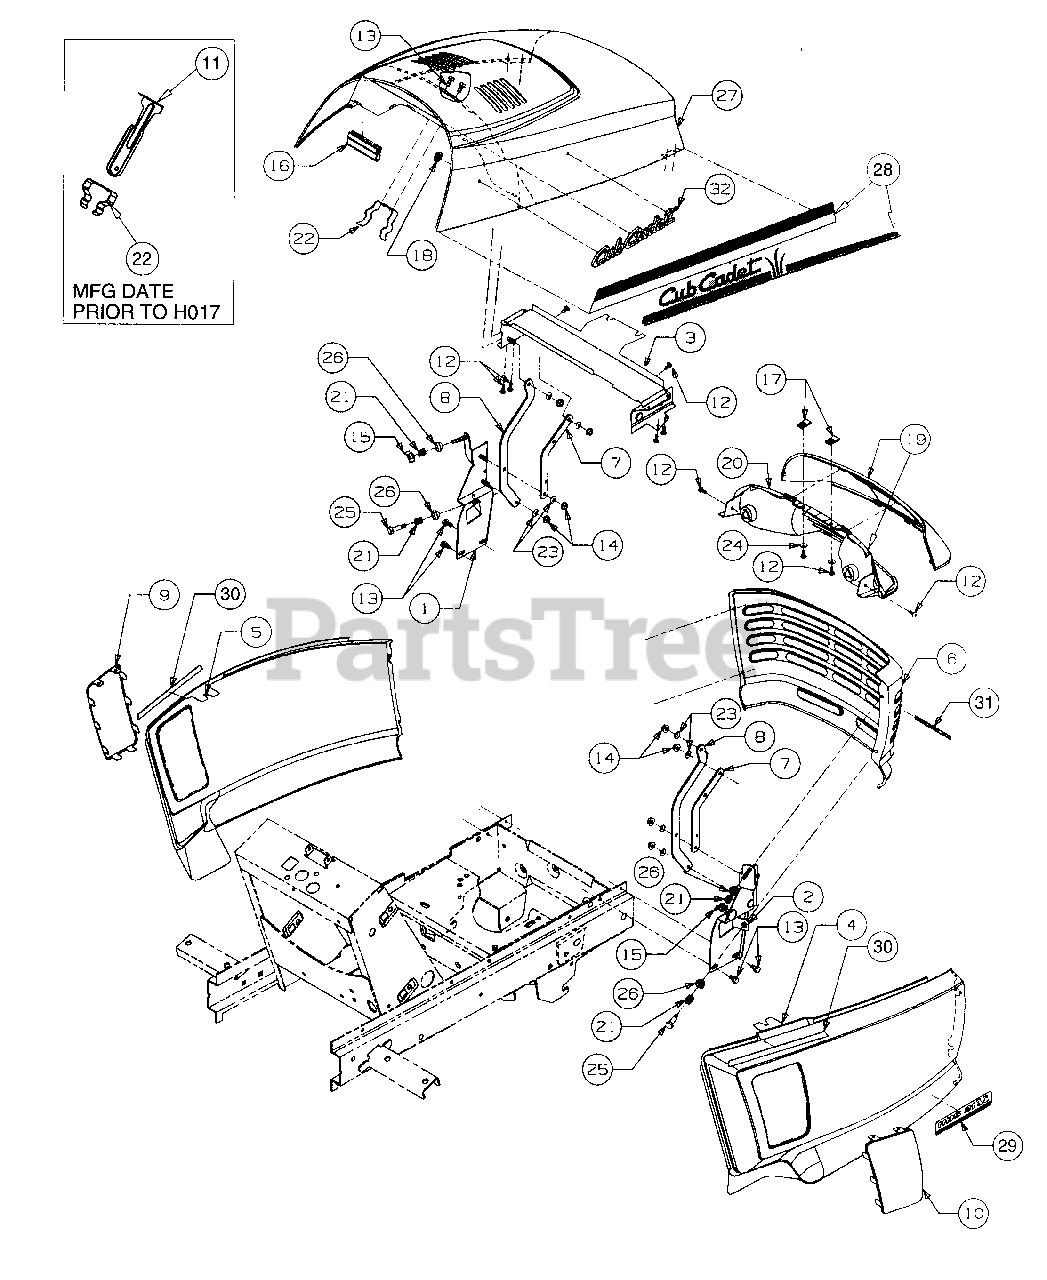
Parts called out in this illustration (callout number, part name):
1	Bracket, Grille LH
2	Bracket, Grille RH
3	Bracket, Upper Hood
4	Panel, RH Side
5	Panel, LH Side
8	Link, Long Hood
9	Screen, LH Panel
10	Screen, RH Panel
11	Guide, Hood
12	Screw, Truss Mach Tapp, #10 x .50
13	Screw, Hex Wash Hd Tapp, 1/4 x .50
14	Nut, Hex Flange Lock, 1/4-20
15	Nut, Wing, 1/4-20
16	Seal, Heat Baffle
17	Nut, U-Type Speed, #10
18	Retainer, Push Nut
19	Headlight Assembly
21	Spring, Compression, .50 OD x .50 Lg
22	Spring, Hood Latch
23	Washer, Spring, .265 x .562 x .025
24	Washer, Flat, .218 x .62 x .063
25	Bolt, Shoulder, .31 Dia x .75 Lg
26	Bushing, Tapered
27	Hood, Series 2000
28	Graphic, Hood, RH
29	Graphic, HDS 2135
30	Strip, Protective
31	Graphic, Warning HOT
32	Script w/Studs, Cub Cadet
